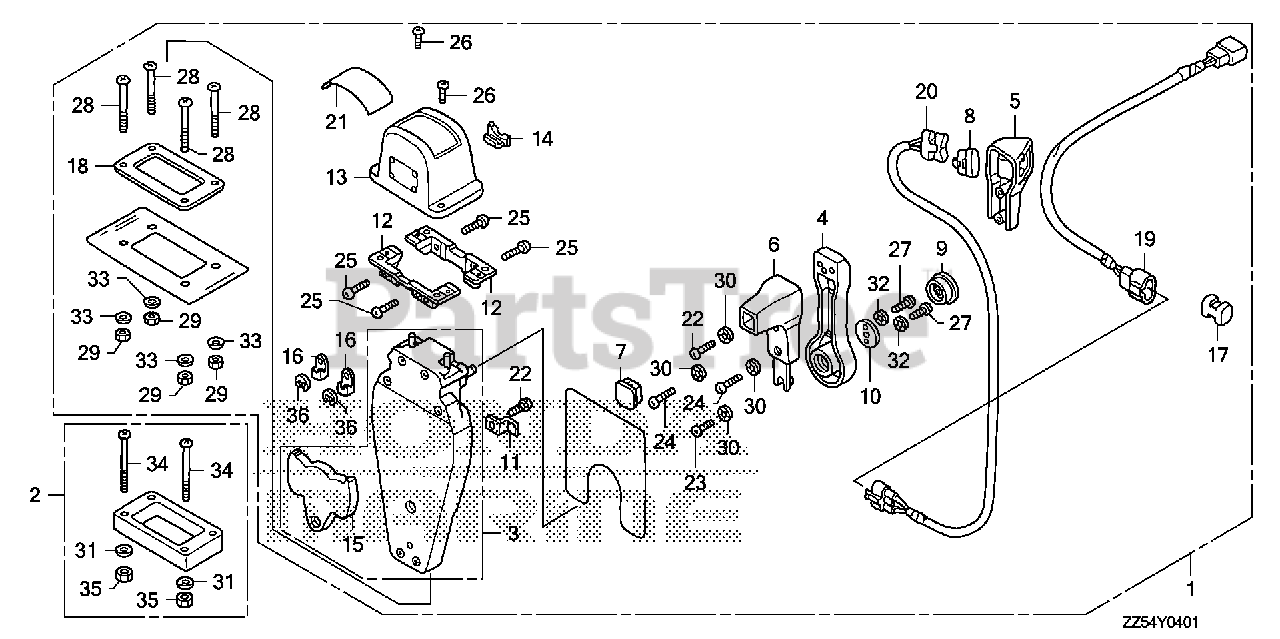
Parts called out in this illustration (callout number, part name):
1	BOX KIT, REMOTE CONTROL (TOP MOUNT SINGLE)(L)
2	SPACER KIT, REMOTE CONTROL BOX (TOP MOUNT SINGLE)
3	HOUSING ASSY., R. (INNER) (TOP MOUNT)
4	HANDLE, REMOTE CONTROL
5	COVER, R. GRIP
6	GRIP, REMOTE CONTROL HANDLE
7	CAP, GRIP
8	CAP, SWITCH
9	BUTTON, THROTTLE
10	PLATE, HANDLE
11	PLATE, CABLE CLAMP
12	BRACKET, REMOTE CONTROL HOUSING
13	HOUSING, REMOTE CONTROL BOX
14	HOUSING, LEAD
15	PLATE, DWELL
16	TERMINAL, CABLE
17	SPACER, CABLE CLAMP
18	GASKET, SINGLE
19	SUB-HARNESS ASSY., POWER TRIM-TILT (B)
20	SWITCH ASSY., POWER TRIM-TILT (B)
21	MARK, REMOTE CONTROL (SINGLE)
22	SCREW, PAN (5X16)
23	SCREW, PAN (5X10)
24	SCREW, PAN (5X20)
25	SCREW, PAN (5X18)
26	SCREW, PAN (4X10)
27	SCREW, PAN (6X18)
28	SCREW, PAN (5X40)
29	NUT, HEX. (5MM)
30	WASHER, LOCK (5MM)
31	WASHER, PLAIN (5MM)
32	WASHER, LOCK (6MM)
33	WASHER, PLAIN (5MM)
34	SCREW, PAN (5X65)
35	NUT, HEX. (5MM)
36	E-RING (6MM)
